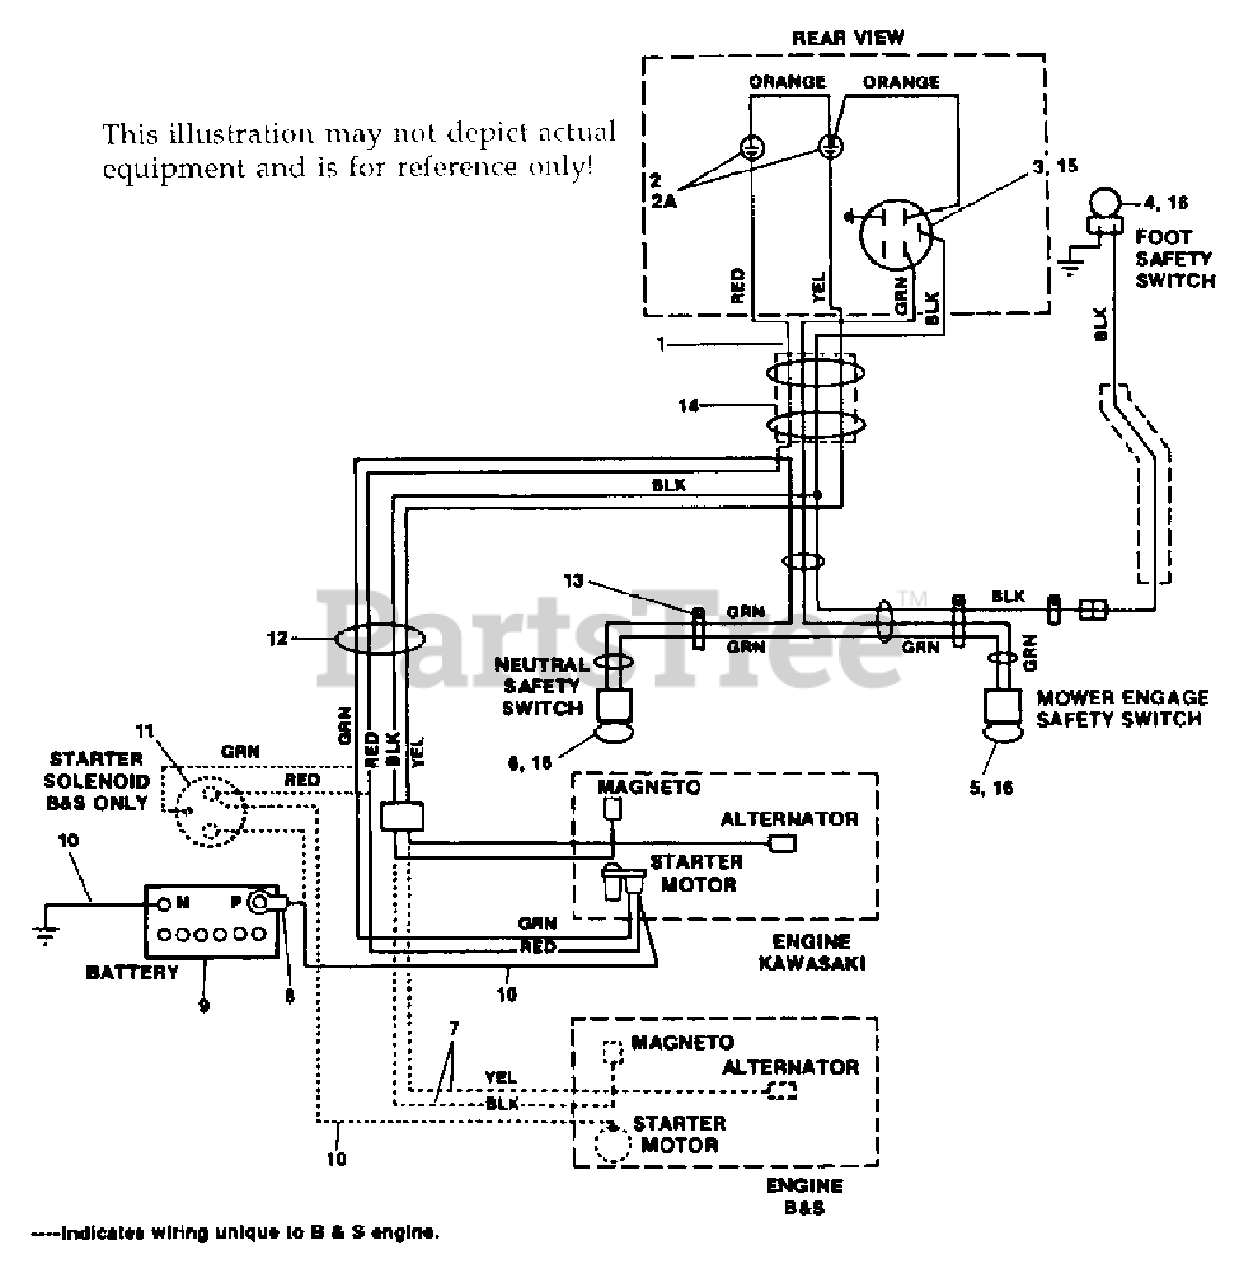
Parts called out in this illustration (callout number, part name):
1	WIRING HARNESS, COMPLETE
2	FUSE HOLDER
2A	FUSE
3	KEY SWITCH
4	FOOT SAFETY SWITCH
5	MOWER ENGAGE SAFETY SWITCH
6	NEUTRAL SAFETY SWITCH
7	HARNESS ADAPTER, B&S ONLY
8	RUBBER BOOT
9	BATTERY
10	BATTERY CABLE
11	STARTER SOLENOID, B&S ONLY
12	CABLE TIE
13	CABLE CLAMP
14	PLASTIC CONDUIT
15	CONNECTOR, STARTER SWITCH
16	CONNECTOR, SAFETY SWITCH
